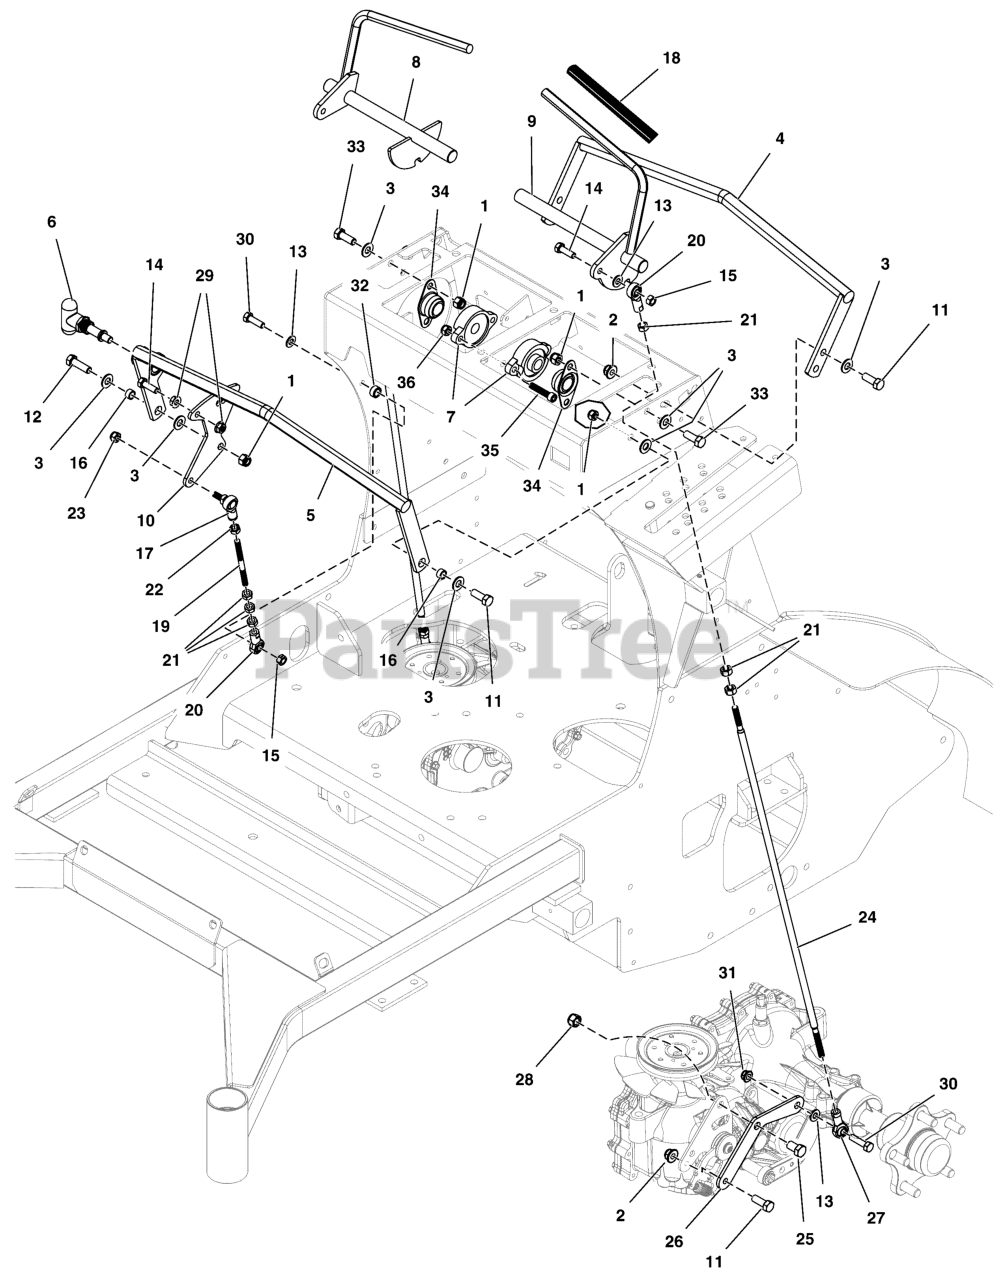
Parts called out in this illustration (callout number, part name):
1	NUT, 3/8-16 HEX NYLON LOCK
2	NUT, 3/8 - 16 HEX NYLOCK FLANGE
3	WASHER, 3/8 SAE
4	WELD, REAR HANDLE, STAND ON - BLK
5	WELD, FRONT HANDLE, STAND ON - BLK
6	PULL PIN, 3/8" DIA X 9/16" STROKE
7	BEARING-FLANGE, 5/8
8	WELD, CONTROL HANDLE, RH, SRS Z2 - BLK
9	WELD, CONTROL HANDLE, LH, SRS Z2 - BLK
10	PLATE, SPEED ADJUSTMENT, SRS - BLK
11	BOLT, 3/8-16 X 1" GD5 CZ
12	BOLT, 3/8-16 X 1-1/4" GD5 CZ
13	WASHER, 5/16" SAE
14	BOLT, 5/16-18 X 1" GRD5 YZ
15	NUT, 5/16-1/8, HEX, CNTR LK, ZINC PHOS/OIL
16	SPACER, .38 X .50 X .27, CZ
17	BALL JOINT, 5/16-24 LH FEMALE W/STUD, BR
18	GRIP, FOAM, .48 x 10 x .125 Black
19	ROD, 5/16-24 X 4.25, CZ
20	BALL JOINT 5/16-24 RH FEMALE BRONZE RACE
21	NUT, Hex, 5/16-24
22	NUT, 5/16-24 HEX, LH
23	NUT, 5/16-24 HEX NYLON LOCK
24	ROD, MOTION CONTROL, STAND-ON
25	BOLT, 7/16-14 X 3/4, GD 5 YZ
26	PLATE, CONTROL MOUNT - BLK
27	BALL JOINT 5/16-24 LH FEMALE BRONZE RACE
28	NUT, 7/16-14 HEX TOP LOCK
29	NUT, 5/16-18 HEX SERRATED FLANGE (SMALL)
30	BOLT, 5/16-18 X 1-1/4" GD5 YZ
31	NUT, 5/16-18 HEX NYLOCK FLANGE NUT
32	SPACER, .33 X .50 X .25, PM, CZ
33	BOLT, 3/8-16 X 3/4" GD5 CZ
34	BEARING, BRONZE, FLANGED, 5/8", FLB10
35	SCREW, SOC HD, 5/16-18 X 1-1/2, BLK
36	NUT, Hex, Nylon Locking, 5/16-18
